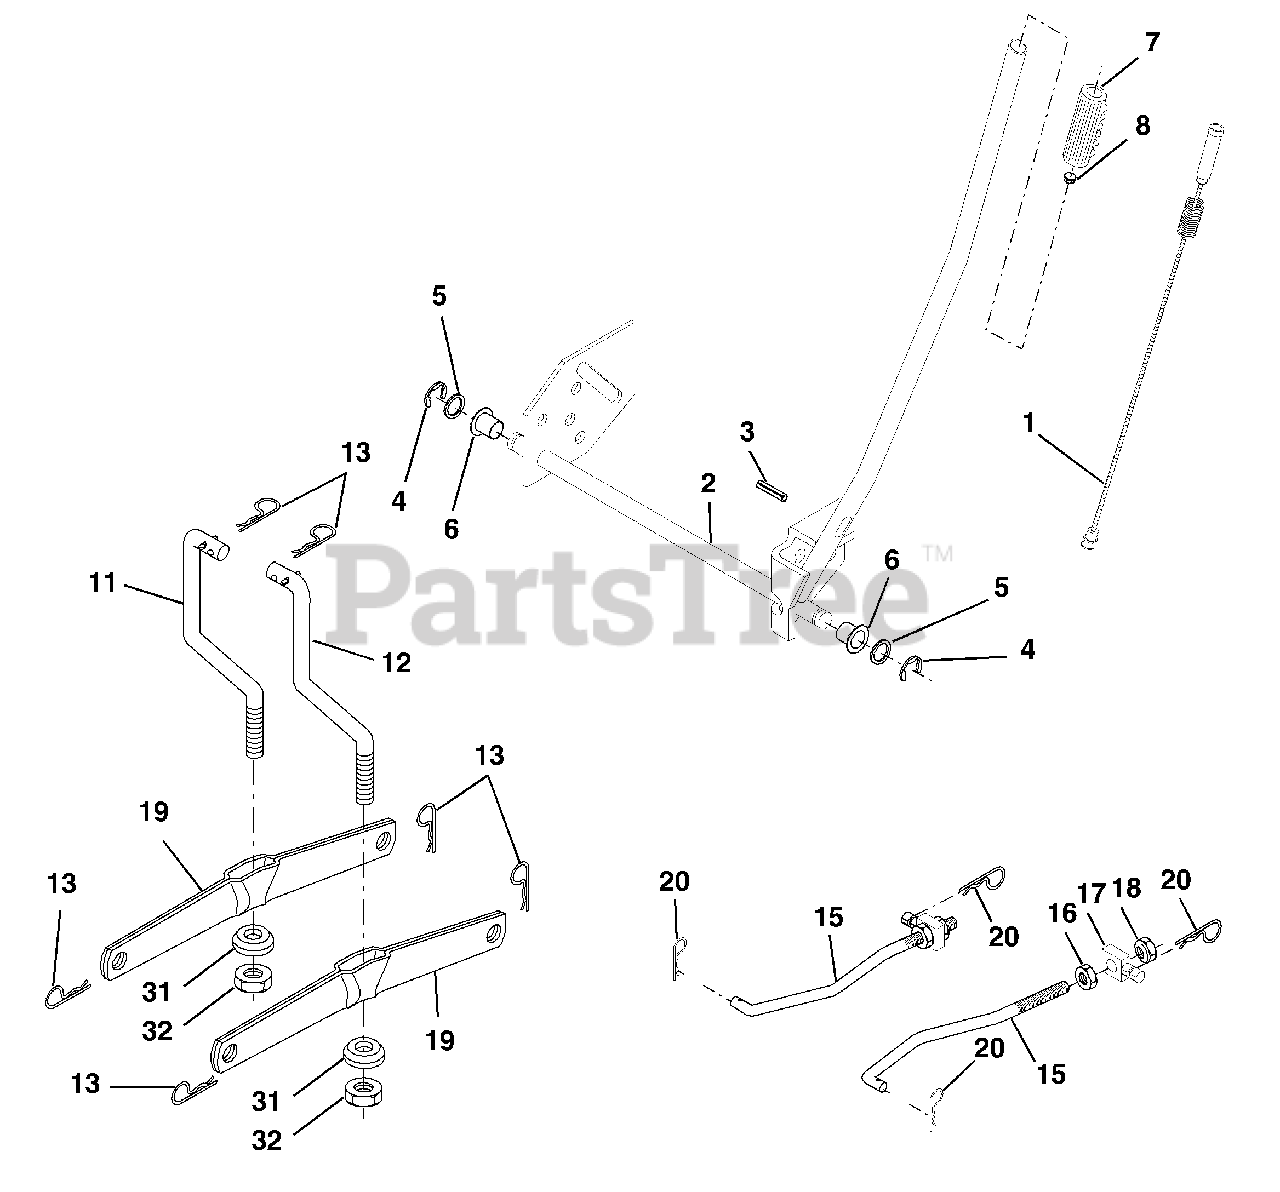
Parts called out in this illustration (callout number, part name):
1	Wire Asm Inner/Sprg w/plunger
2	Shaft Asm Lift RH
3	Pin Groove 1 500 Zinc
4	E Ring #5133-62
5	Washer 21/32 X 1 X 21 Ga
6	Bearing Nylon Blk 629 Id
7	Grip Handle Bicycle Matte Blk
8	Button Plunger Black
11	Link Lift LH Fixed Length
12	Link Lift RH Fixed Length
13	Retainer Spring
15	Link Front
16	Nut Jam Hex 1/2-13 Unc
17	Trunnion
18	Nut Lockw/Wsh 1/2-13 Unc
19	Arm Suspension Rear
20	Retainer, Spring
31	Bearing Pvt Lift
32	Nut Crownlock 3/8-24
